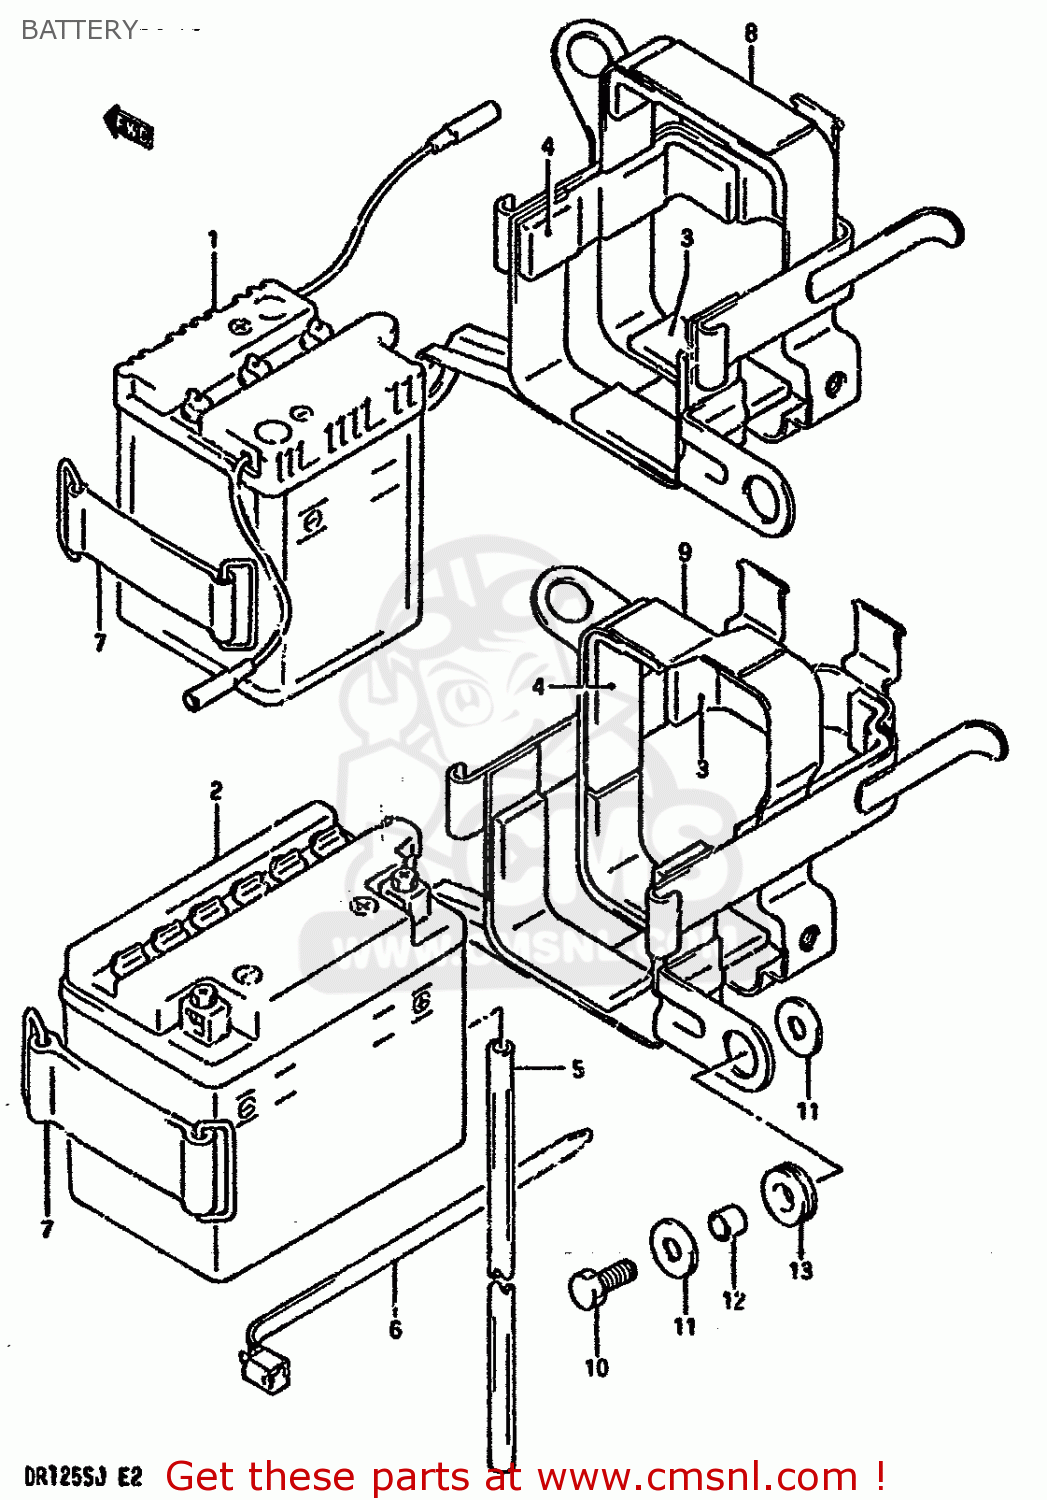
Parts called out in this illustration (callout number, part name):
1	BATTERY ASSY(6N4-2A4.2AH)
2	BATTERY ASSY(YB4L-B,12V4.2AH)
3	PROTECTOR,BATTERY
4	PROTECTOR,20X9
5	HOSE,BATTERY EXHAUST
6	CLAMP(L:165)
7	BAND
8	HOLDER COMP,BATTERY
9	HOLDER,BATTERY
10	BOLT
11	WASHER (6.5X20X1.2)
12	SPACER (6X9X5)
13	CUSHION
